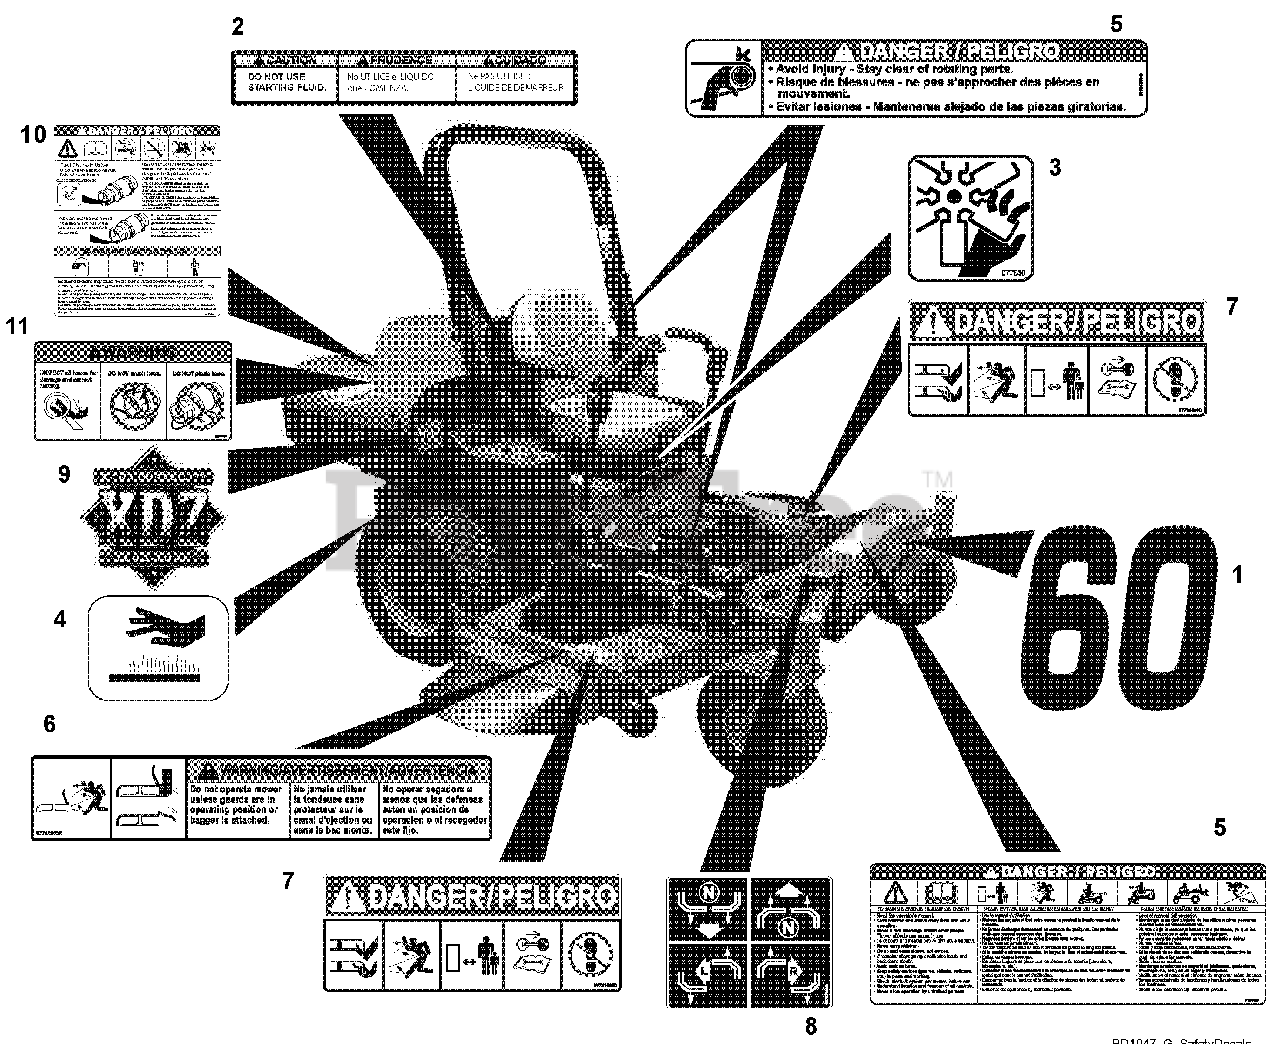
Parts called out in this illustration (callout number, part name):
1	Decal, 60"
2	Decal, No Starting Fluid
3	Decal, Danger Fan
4	Decal-Hot Surface
5	Set, Decal – Common Danger/Fuel
6	Decal, Warning
7	Decal, Mower Pan Head Danger
8	Decal – Instructional
9	Decal, XDZ
10	Decal, Tank Specification
11	Decal, Hose Inspection
